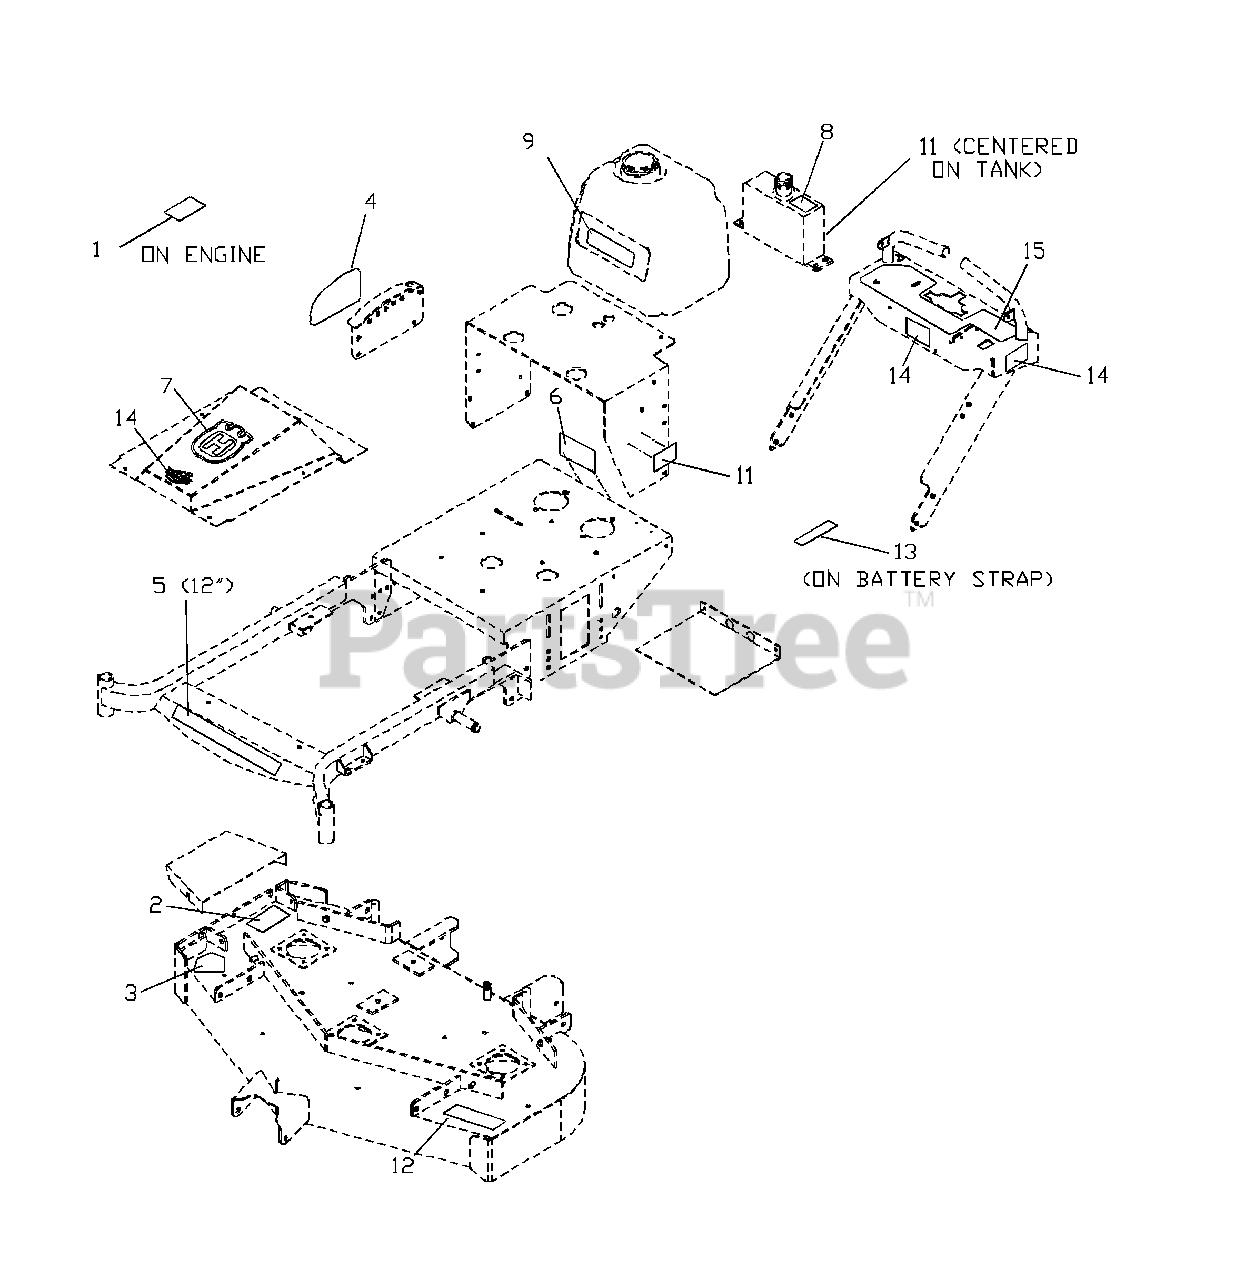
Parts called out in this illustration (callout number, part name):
1	DECAL, PROP 65
2	DECAL, DANGER
3	DECAL, WARNING
4	DECAL, HEIGHT ADJ.
5	DECAL, HUSQVARNA
6	DECAL, BELT DRIVES
7	DECAL, LARGE CROWN
8	DECAL, MOBIL 1
9	DECAL, WHF4215
9	DECAL, WHF4818
9	DECAL, WHF5218
11	DECAL, CROWN
12	DECAL, NASCAR
13	DECAL, BATTERY
14	DECAL, ETS
15	DECAL, CONSOLE
